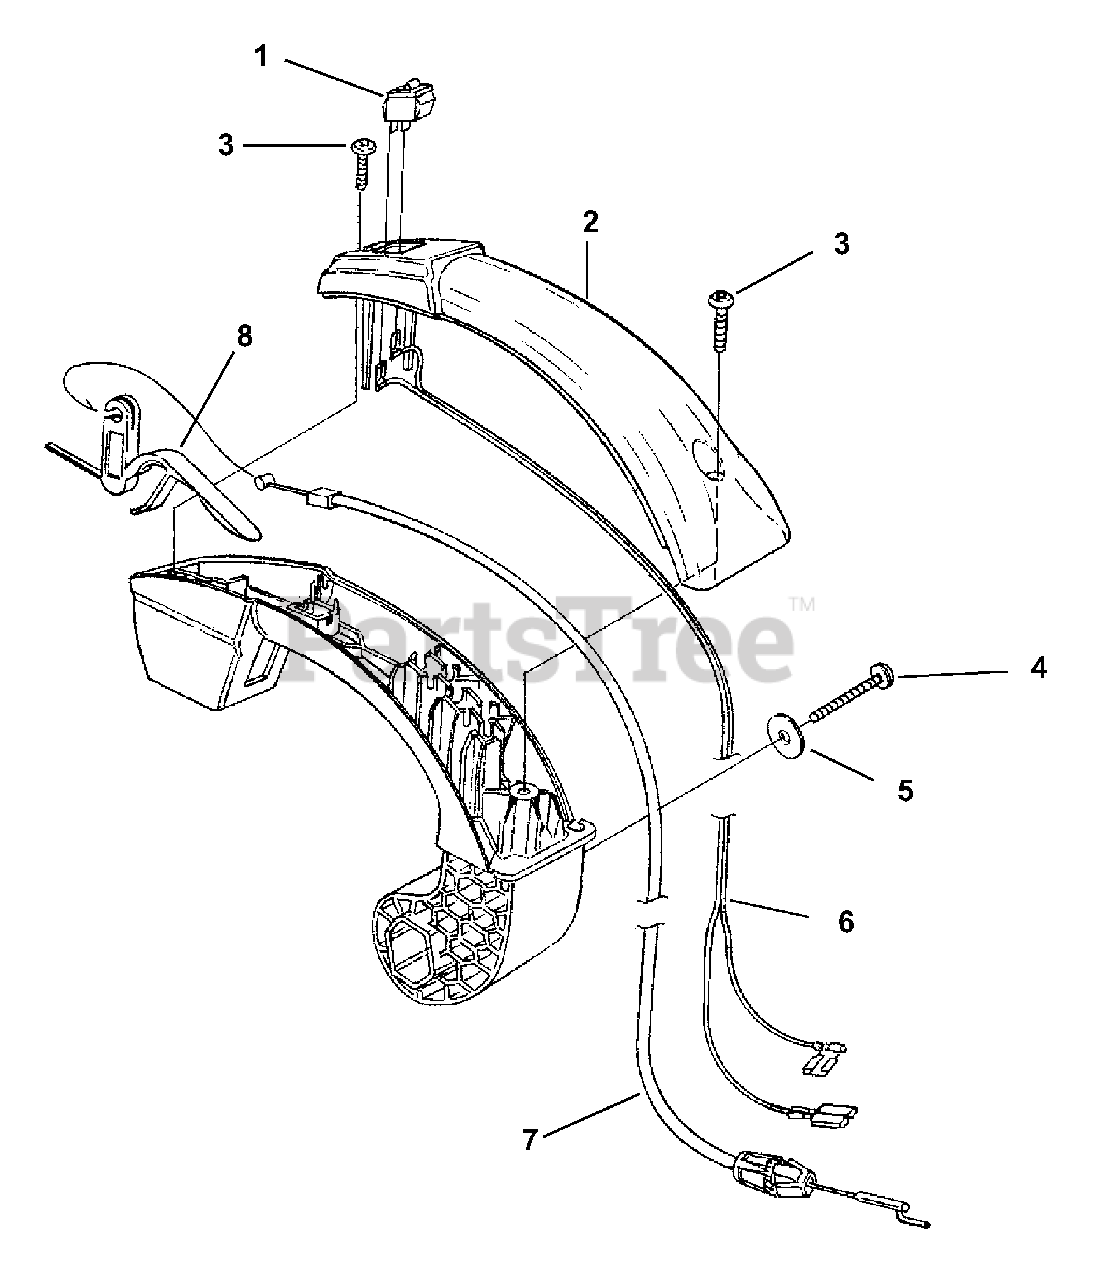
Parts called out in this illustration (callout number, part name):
1	Switch, Rocker (Stop)
2	Handle Cover
3	Screw, Thread Forming (8-16 X 1/2)
4	Screw, Thread Forming (10-14 X 7/8)
5	Washer, Flat
6	Kill Switch Lead
7	Cable, Throttle
8	Trigger
